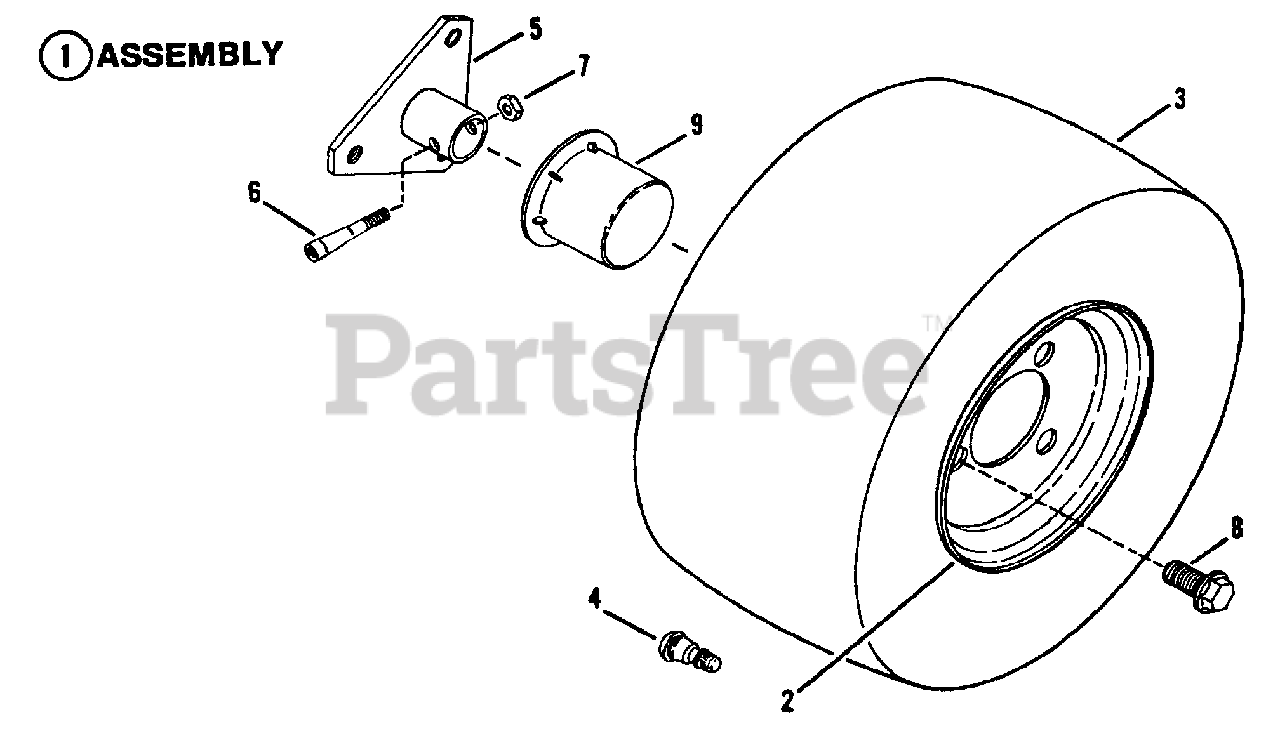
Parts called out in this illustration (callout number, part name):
1	ASSEMBLY, Rear Tire & Rim
2	RIM, LT16 Rear Wheel
3	TIRE, 21 x 7.00 x 10
4	VALVE, Air
5	HUB, Rear Wheel
6	BOLT, Tapered
7	NUT, 5/16-24 Lock
8	BOLT, Lug (1/2-20 x 3/4" HHCS)
9	HUB-CAP
